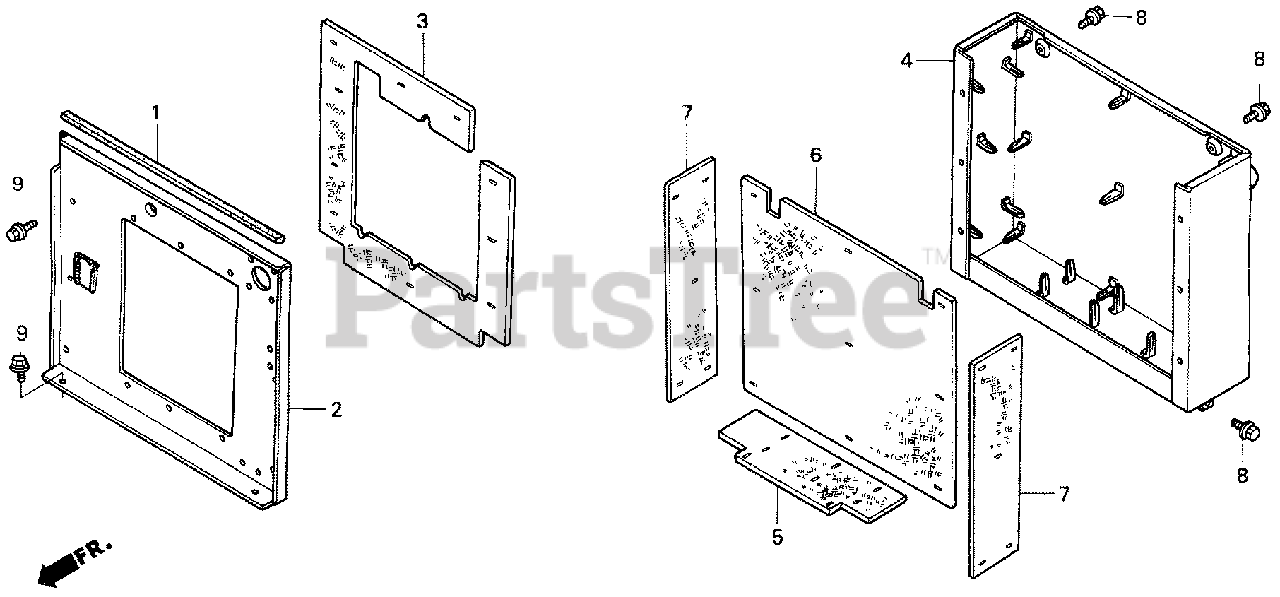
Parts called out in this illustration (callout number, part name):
1	SEAL, COVER (UPPER)
2	COVER, RADIATOR
3	INSULATOR, RADIATOR COVER (LOWER)
4	COVER, RR. *NH213M* (MILD SILVER METALLIC)
5	INSULATOR, RR. COVER (LOWER)
6	INSULATOR, RR. COVER (UPPER)
7	INSULATOR B, RR. COVER (UPPER)
8	BOLT, FLANGE (8X16)
9	BOLT, FLANGE (8X16)
